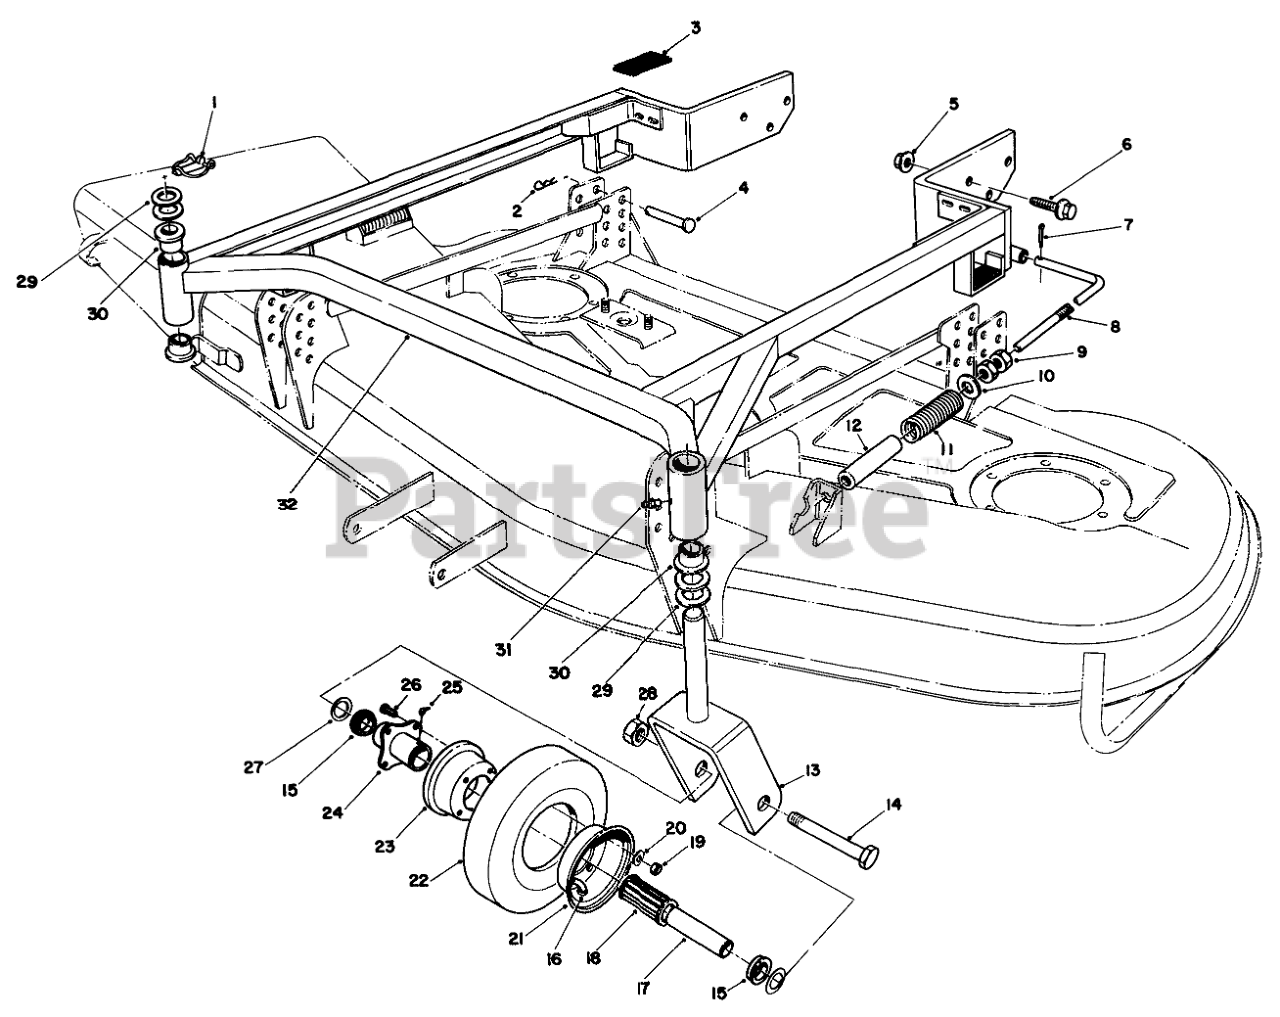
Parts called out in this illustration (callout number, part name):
1	PIN-LYNCH
2	PIN-HAIR
3	Cushion-Rubber
4	PIN-CLEVIS
5	NUT-LOCK, FLANGE
6	SCREW-HHF
7	PIN-COTTER
8	ADJUSTING SHAFT
9	NUT-JAM
10	WASHER
11	SPRING-COMPRESSION
12	SLEEVE-TUBE, 36 INCH
13	FORK-Castor
14	SCREW-HH
15	RETAINER
17	Bushing-Spanner
18	BEARING-ROLLER
19	NUT-HEX
20	WASHER-LOCK
21	WHEEL HALF-FEMALE
22	TIRE-8 Inch (4-PLY)
23	WHEEL HALF-MALE
24	HUB-CENTERED
25	FITTING-GREASE
26	WHEEL BOLT
27	SPACER-WHEEL
28	NUT-LOCK
29	WASHER-THRUST
30	Bushing
31	FITTING-GREASE
32	Frame-Carrier (Incl. Ref. #30)
